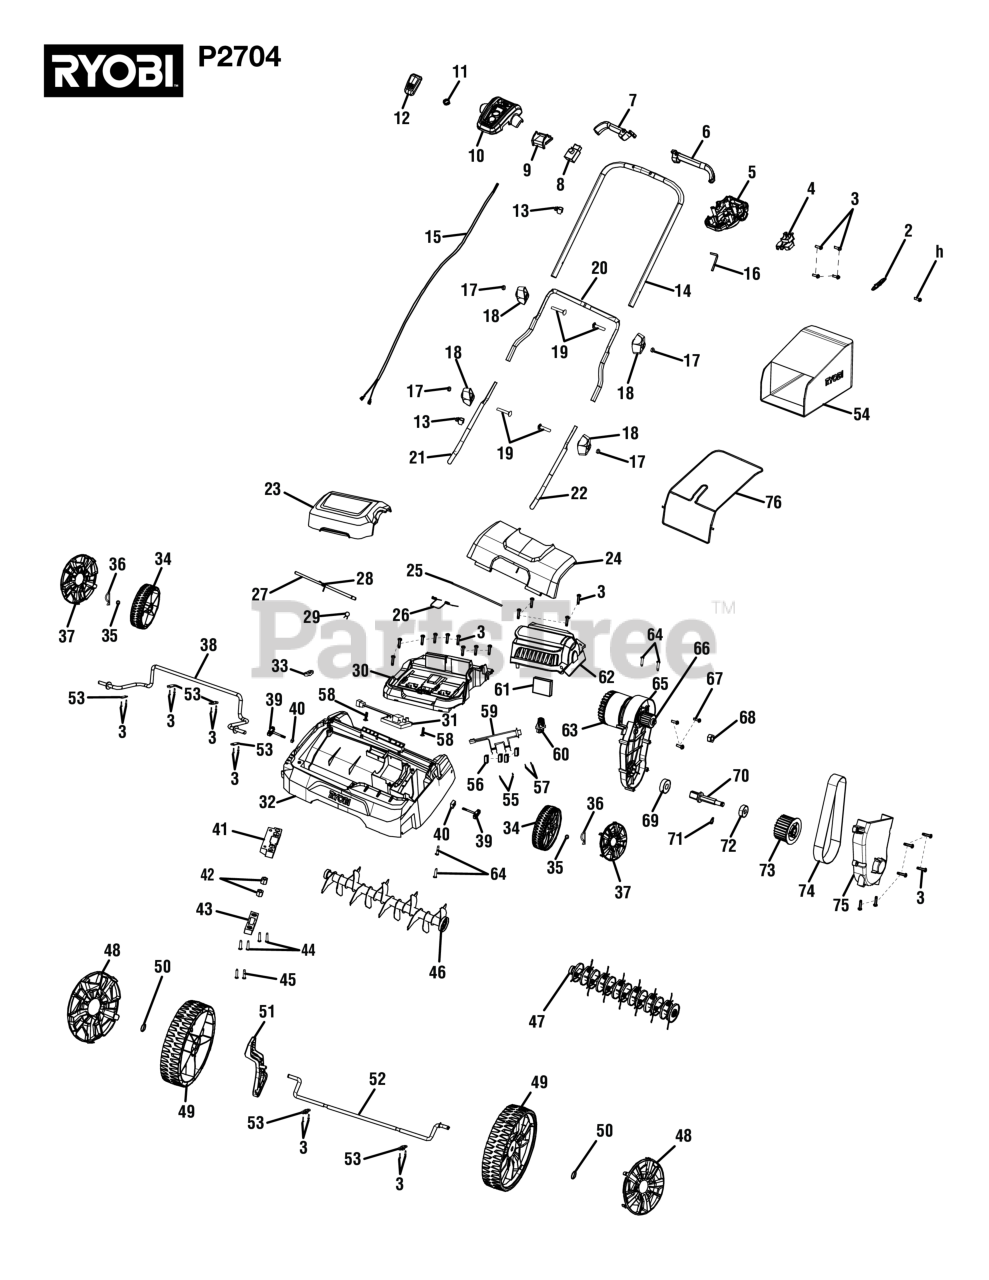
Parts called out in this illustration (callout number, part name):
1	Screw (ST4.2 x 12 mm)
3	Screw (ST4.2 x 15 mm)
4	Switch Middle Plate
5	Switch Bottom Cover
6	Right Trigger
7	Left Trigger
8	Electronic Switch
9	Waterproof Cover
10	Switch Top Cover
11	Switch Spring
15	Wire Component
16	Wrench (45#)
18	Rotary Knob
20	Middle Handle
21	Right Bottom Handle
22	Left Bottom Handle
23	Battery Cover
25	Rear Door Axle
26	Rear Door Spring
27	Battery Cover Axle
28	Battery Cover Spring
29	Spring Ring
31	Circuit Board Assembly
34	Front Wheel
35	Flat Washers (ID8 x OD16 x 1.6t)
36	Butterfly Pin
37	Front Wheel Cover
38	Front Wheel Axle
39	Rotary Knob
41	Press Blade Shaft Base
42	Screw (M6 x 9.2 mm)
43	Press Blade Shaft Cover
44	Screw (ST4.2 x 1.8 mm)
45	Screw (M6 x 20 mm)
46	Dethatcher Blade
47	Aerator Roller
48	Rear Wheel Cover
50	Bearing Holder
51	Height Adjustment Lever
52	Rear Wheel Axle
53	Press Plate
55	Screw (ST4.2 x 15 mm)
57	Screw (ST3 x 12 mm)
58	Screw (ST4 x 12.5 mm)
59	Wiring Component
62	Battery Cover
64	Screw (ST4.8 x 18 mm)
65	Pulley Casing
66	Big Belt Pulley
69	Bearing (6000RS)
72	Bearing (608RS)
73	Synchronous Pulley
75	Pulley Cover
76	Grass Catcher Frame
